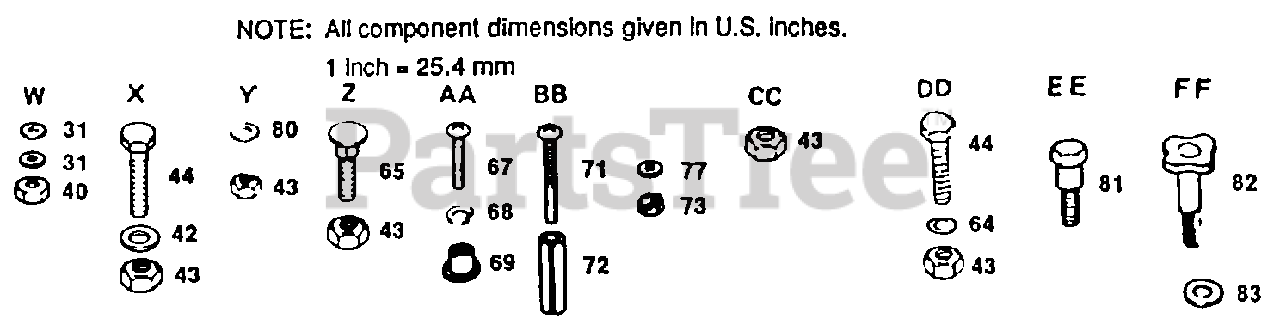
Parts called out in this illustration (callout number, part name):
31	WASHER PM
42	WASHER
44	BOLT
64	WASHER
65	BOLT
67	SCREW
68	LOCKWASHER
69	WELDNUT
71	SCREW
72	SPACER LT
77	WASHER
80	WASHER
82	"KNOB 1/2"" YT"
83	WASHER
